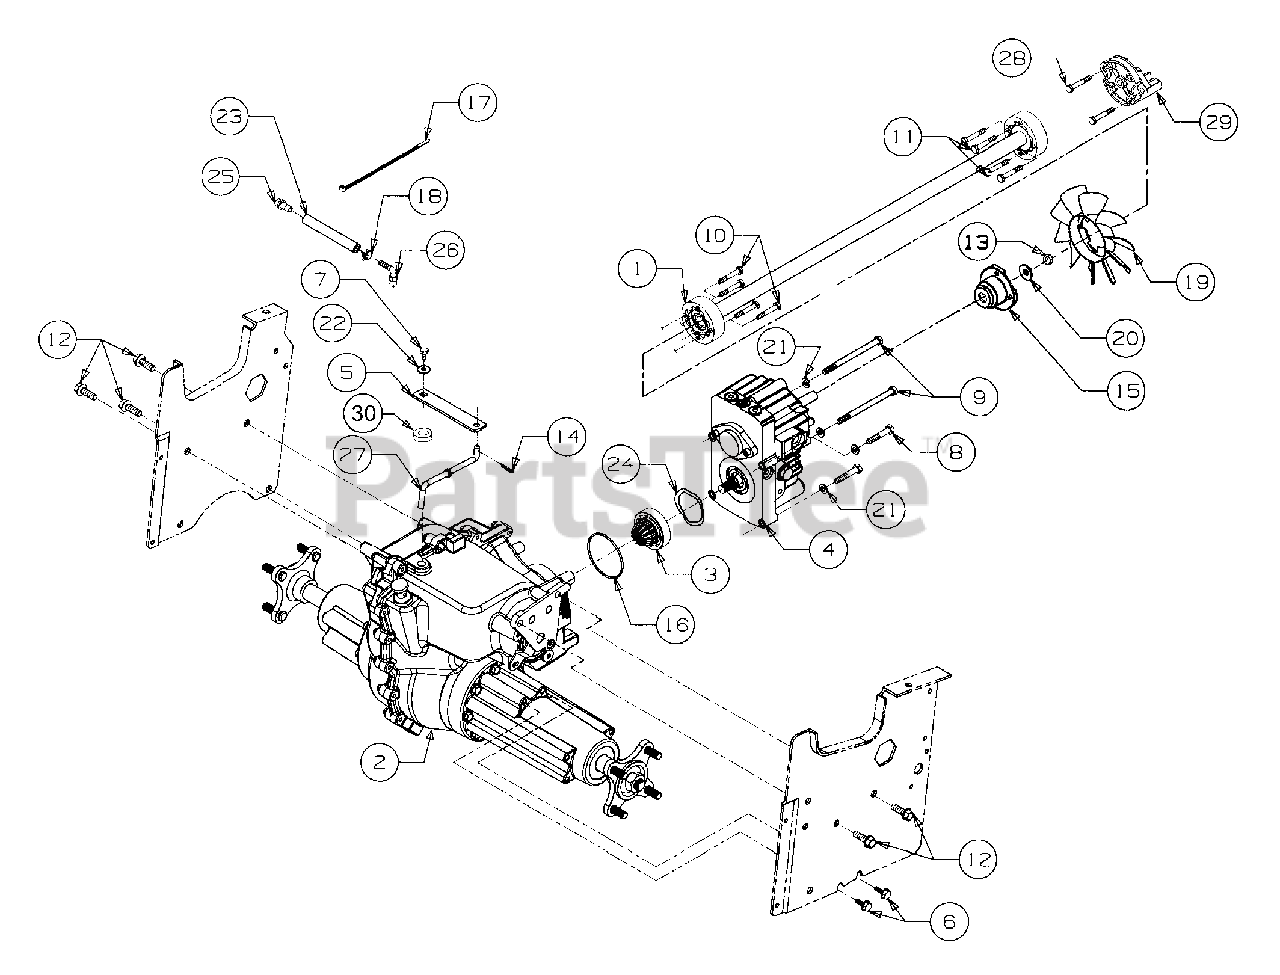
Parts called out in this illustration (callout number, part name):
1	Shaft Assembly, Drive, 28.25 Lg
2	Transmission Assembly, Hydro
3	Pinion Assembly, Input
4	Pump, Hydrostatic
5	Arm, Hydro Dump
6	Screw, Hex Wsh Tap, 5/16-18 x .75
7	Screw, Hex Wsh Tap, 1/4-20 x .75
8	Screw, Hex Cap, 5/16-18 x 1.75 GR5
9	Screw, Hex Cap, 5/16-18 x 4.5 GR5
10	Screw, Hex Patch, 1/4-20 x 1.25 GR5
11	Screw, Hex Patch, 1/4-20 x 1.62 GR5
12	Screw, Hex Wsh Tap, 3/8-16 x 1.25
13	Nut, Hex Top Lock Jam GR5, 1/2-20
14	Pin, Internal Cotter, 5/16 Dia x 1.12
15	Adapter, Pump
16	O-Ring, 2.75 x .103
17	Tie, Self-Clinch Cable
18	Clamp, Hose
19	Fan, 10 Blade Cooling
20	Washer, Bell, 1/2 ID
21	Washer, Lock, 5/16
22	Washer, Bell, .265 x .75 x .062
23	Line, Fuel, 7in (10ft Bulk)
24	Washer, Wave, 1.96 x 2.44 x .06
26	Fitting, Elbow
27	Rod, Hydro Disengagement
28	Screw, Hex Patch, M10-1.50x 90mm
29	Adapter, Drive Shaft
30	Spacer, 1/2 x 1.0 x .32
